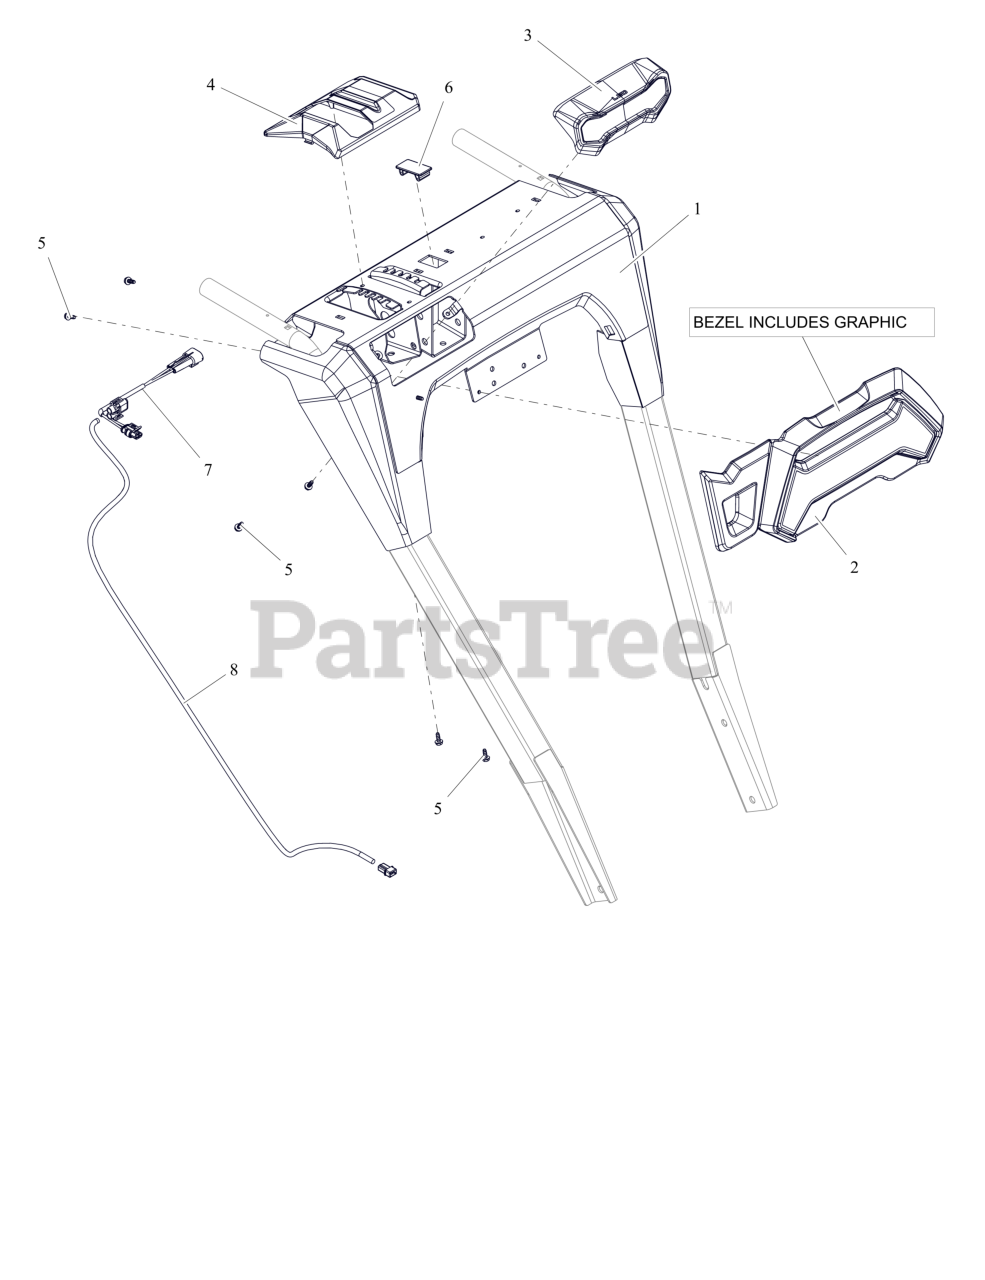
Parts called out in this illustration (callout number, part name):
1	PANEL, DASH-FRICTION PB W/DECAL
2	BEZEL- LARGE - POWER BRUSH
3	HEADLIGHT ASM- LED
4	BEZEL, SHIFT FRIC W/DECAL
5	SCR, PLASTIC #10X.50
6	PLUG,DASH PANEL
7	HARNESS- WIRE - LED LT JUMPER
8	HARNESS, LIGHT - DELUXE
